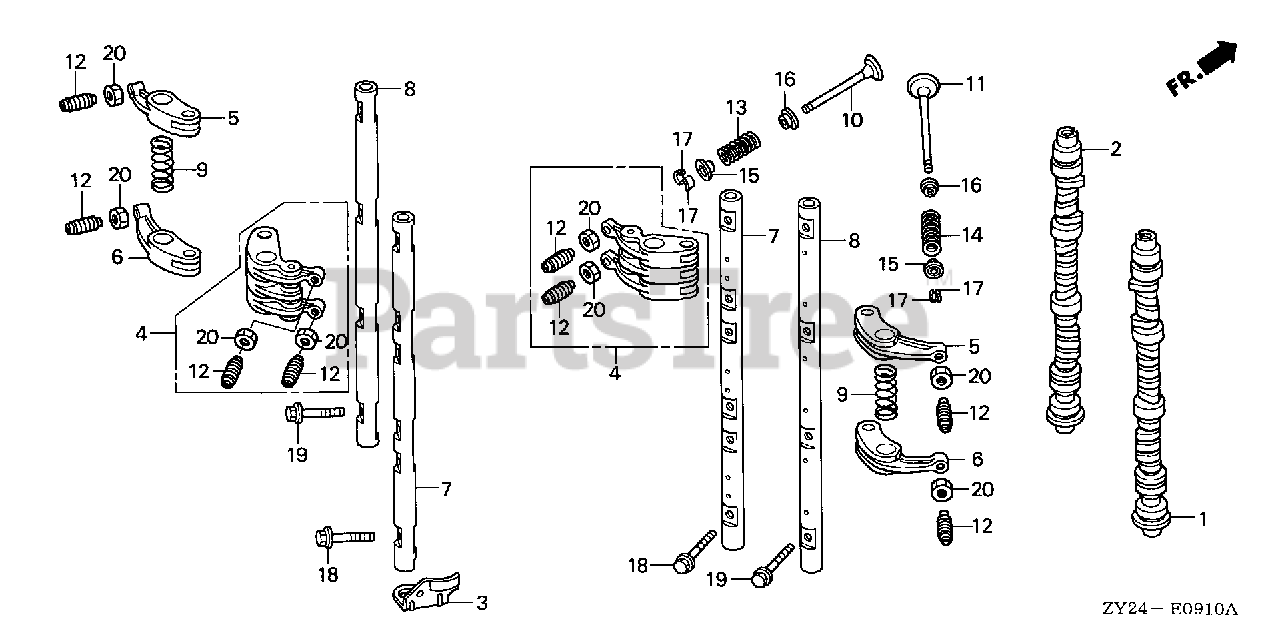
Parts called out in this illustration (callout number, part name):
1	CAMSHAFT, R.
2	CAMSHAFT, L.
3	ARM, FUEL PUMP ROCKER
4	ARM ASSY., IN. ROCKER
5	ARM A, EX. ROCKER
6	ARM B, EX. ROCKER
7	SHAFT, IN. ROCKER ARM
8	SHAFT, EX. ROCKER ARM
9	SPRING, ROCKER ARM
10	VALVE, IN.
11	VALVE, EX.
12	SCREW, TAPPET ADJUSTING
13	SPRING, IN. VALVE (GRAY) (ASSOCIATED SPRING)
14	SPRING, EX. VALVE (YEL/GRN) (ASSOCIATE)
15	RETAINER, VALVE SPRING
16	SEAT, VALVE SPRING
17	COTTER, VALVE (FUJI VALVE)
18	BOLT, FLANGE (8X30)
19	BOLT, FLANGE (8X40)
20	NUT, TAPPET ADJUSTING
